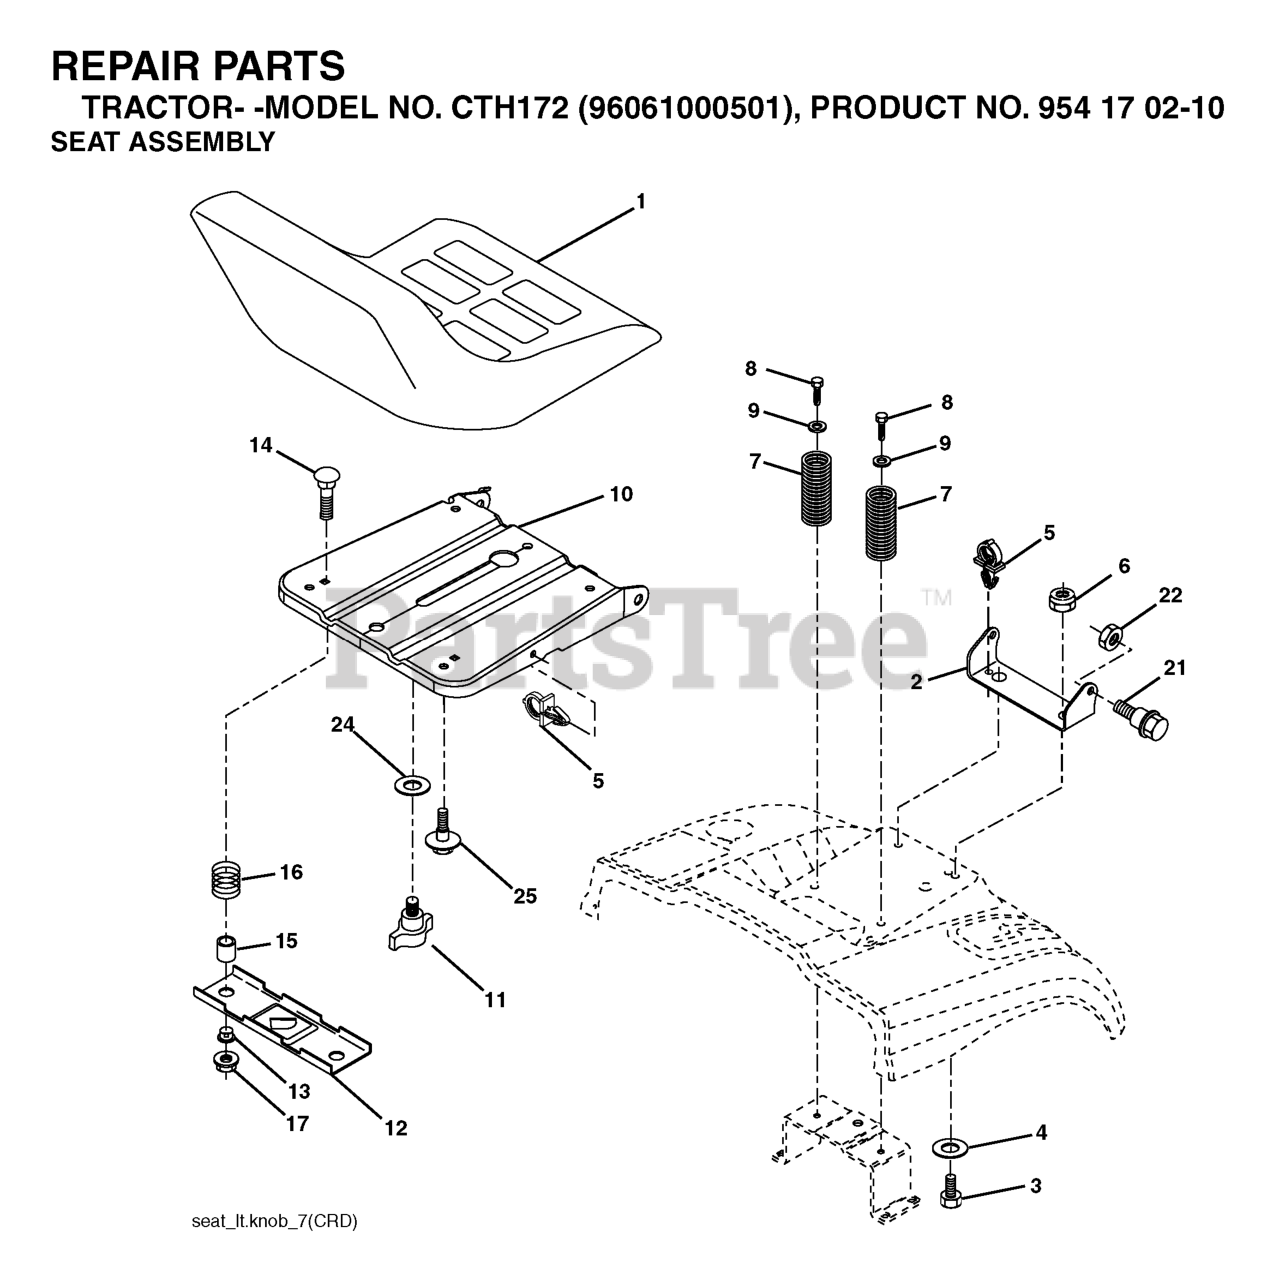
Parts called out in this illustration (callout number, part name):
1	SEAT
2	SEAT PIVOT BRKT
3	BOLT, HEX 3/8-16X1
6	NUT
7	SPRING COMPRESSION
8	SCREW 3/8-16X1
9	WASHER
10	PAN SEAT
11	KNOB.SEAT.ADJ.WINGNUT
12	BRKT SWITCH
14	BOLT.ROUND.HEAD.SQUARE.NECK
15	SPACER SPLIT
16	SPRING COMPRESSED
17	NUT T
21	BOLT.SHOULDER.5/16-18
22	NUT.71038.31-18.HEX.NYLOCK
25	BOLT,SHOULD
